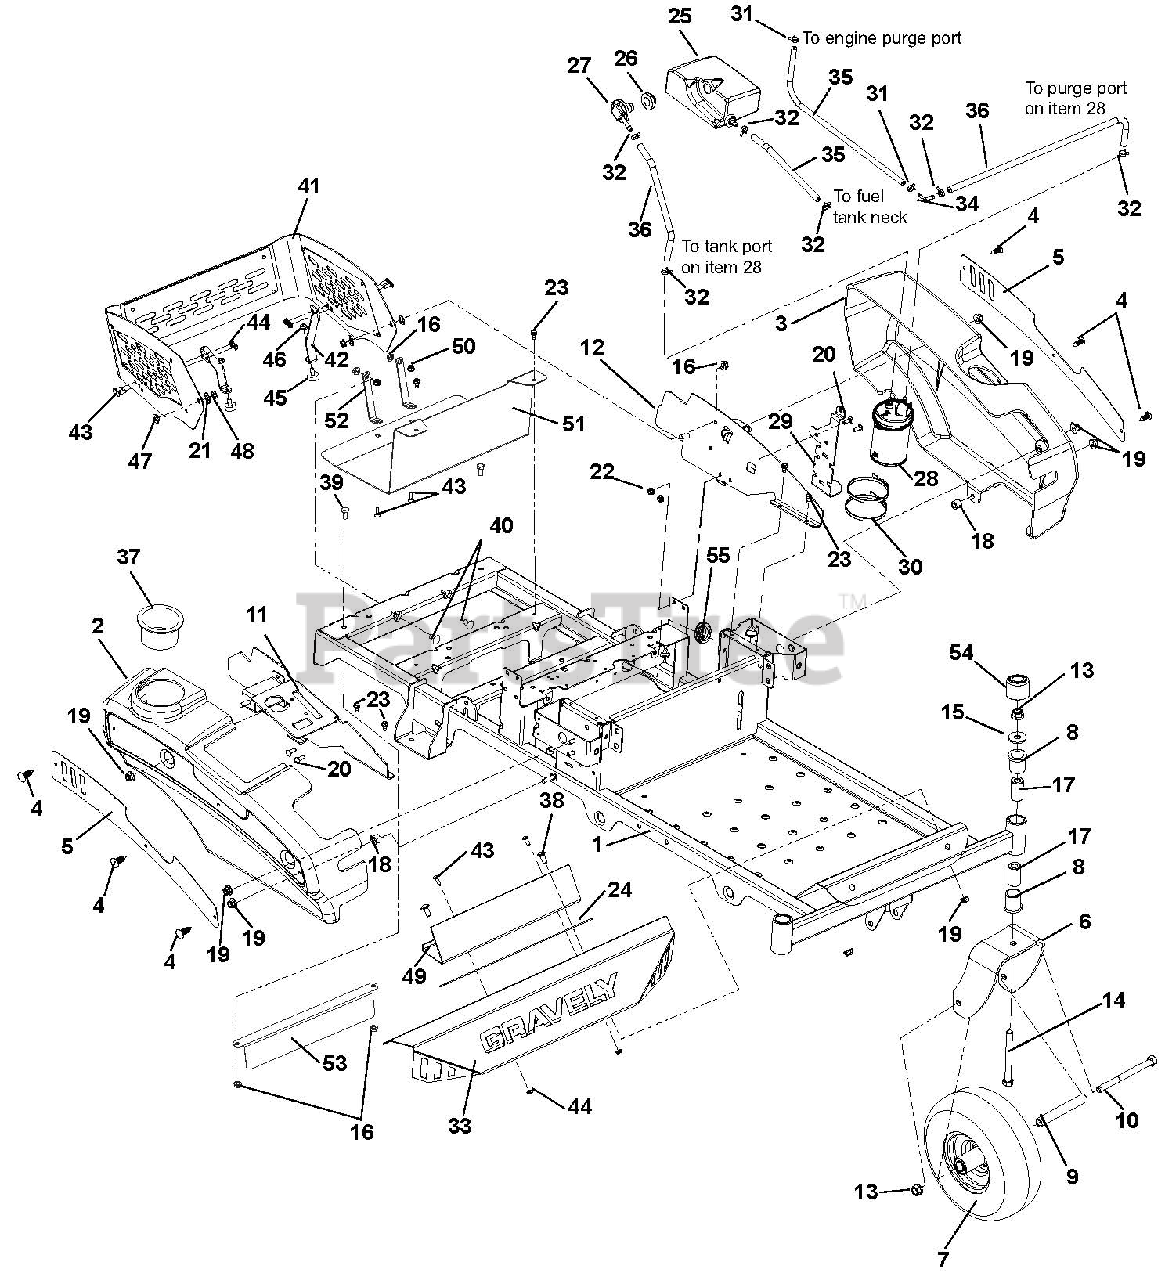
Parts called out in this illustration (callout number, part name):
1	KIT, ZOOM/ZT FRAME W/ DECALS
2	FENDER, RH
3	FENDER, LH
4	RIVET, .25 NYLON PANEL
5	PLATE, FENDER ZT
6	WMT, CASTER FORK
7	ASM, WHL/TIRE 11X4.00-5
7	TIRE, 11X4-5 TURF TREAD
7	TUBE 11 X4.0-5 TR87
8	BSHG-FLG 1.00X1.25X1.50X1.50
9	SPACER, ROLLED WHEEL
10	@BLT-HEX .50-13X6.50 GR5 YWZC
11	WLDMT, RH FENDER MOUNT
12	WLDMT, LH FENDER MOUNT
13	@NUT-LK-TOP-FLG .50-13 YWZC
14	@BLT-HEX .50-13X5.00 GR5 YWZC
15	WSHR-FL-STL.511X1.441X.125 YWZ
16	@NUT-LK-TOP-FLG .38-16 YWZC
17	SPACER, CASTER .50X1.00X1.84
18	BSHG-SLV .391X.688X.52 PM
19	@NUT-LK-NYL-FLG .31-18 YWZC
20	@BLT-RDHDSQNK .25-20X.75 G5YZ
21	WSHR-FL-NYL .518X1.000X.080
22	@NUT-LK-NYL-FLG .25-20 YWZC
23	SCR-TAP .25-20X.50 HWH TR YWZ
24	GRIP, ADHESIVE (1" X 16" BLK)
25	EXPANSION TANK SUB ASSY
26	GROMMET, REMOTE VENT NITRILE
27	VALVE, COMBINATION
28	HOSE, .25 LOW-PERM BULK GAS
29	HOSE, .25 LOW-PERM BULK GAS
30	CARBON CANISTER, 300CC
31	BRKT-MOUNT, CANISTER BBZ
32	P-PLASTIC TIE STRAP LARGE
33	CLAMP-HOSE, SPRING .188
34	CLAMP, FUEL LINE
35	WLDMT, 48" DECK 2014 PROSTANCE
36	FITTING-3/16X1/4 90DEGREE VAC
37	HOSE, .188 LOW-PERM BULK GAS
38	HOSE, .25 LOW-PERM BULK GAS
39	CUPHOLDER
40	BLT-RDHDSQNK .50-13X7.00
41	@BLT-HEX .38-16X1.00 GR5 YWZC
42	@BLT-RDHDSQNK .38-16X1.00 G5YZ
43	ASSEMBLY, ENGINE WRAP ZT
44	BRACKET, ENGINE WRAP FOOT
45	@BLT-RDHDSQNK .25-20X.50 G5YZ
46	NUT-LK-CTR-FLG .25-20 YWZC
47	BUMPER, RUBBER
48	@NUT-SPNLK-FLG .312-18 YWZC
49	BSHG-FLG .325X.499X.3X.875
50	@NUT-LK-CTR-FLG .31-18 YZ GR F
51	PLATE, BACK FOOT-PLATE
52	@NUT-LK-TOP-FLG .25-20 YWZC
53	GUARD, HEAT SHIELD (ZOOM/ZT)
54	STRAP, HEAT SHIELD (ZOOM/ZT)
55	GUARD, HOT SURFACE (ZOOM/ZT)
56	CAP, DUST
57	GROMMET 1.0ID X 1.38 OD
